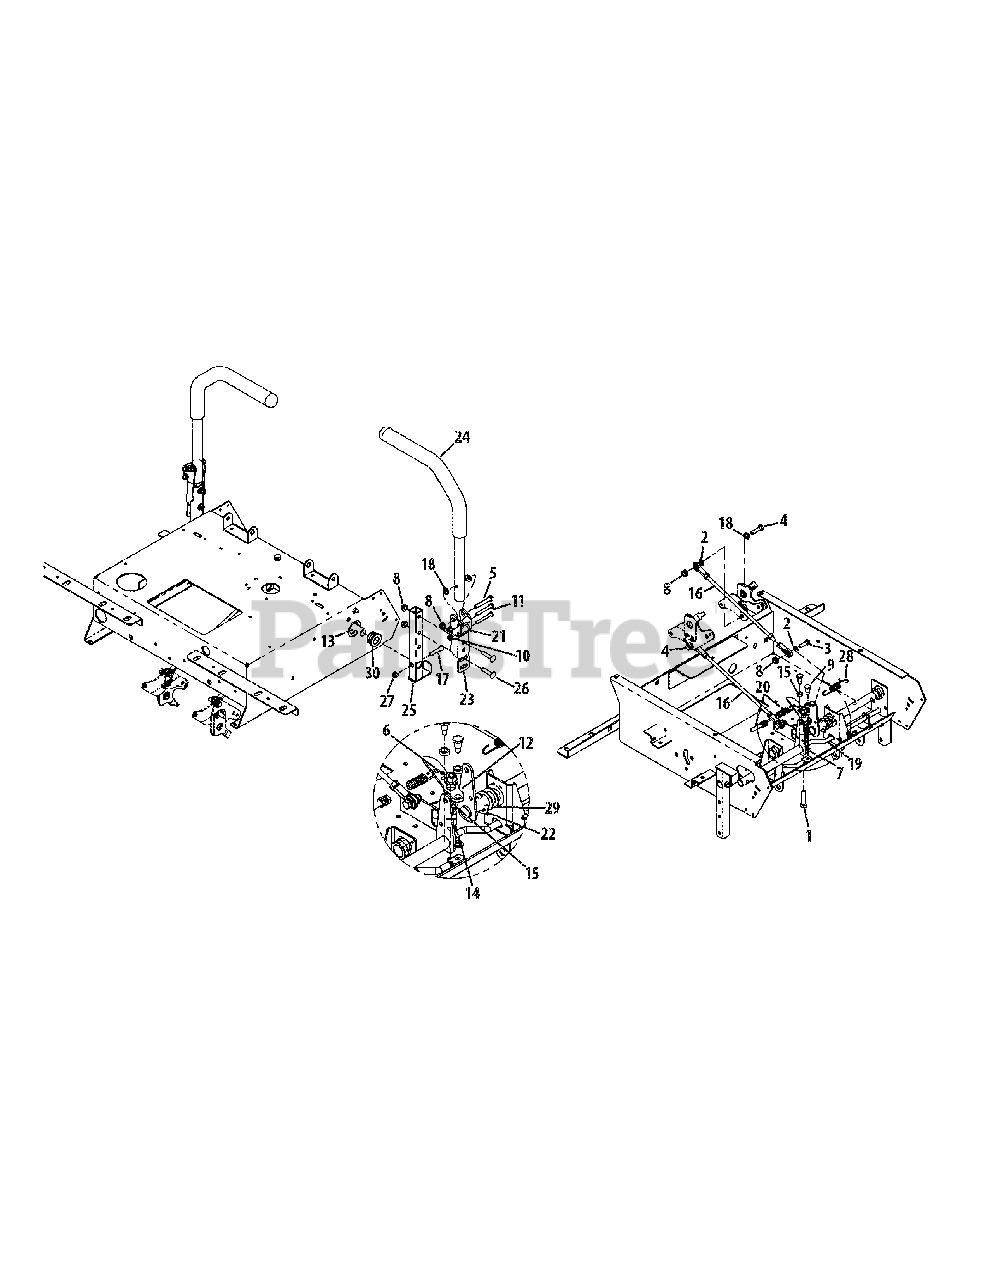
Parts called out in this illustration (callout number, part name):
1	Hex Cap Screw, 3/8-16 x 1-1/2
2	Flat Washer, 5/16
3	Hex Head Cap Screw, 5/16-18 x 1.00
4	Hex Screw, 5/16-18 x 1-1/4
5	Hex Cap Screw, 5/16-18 x 2.00
6	Flange Lock Nut, 3/8-16
7	Flat Washer, 1.4 x .630 x .0515
8	Lock Nut, 5/16-18
9	Shoulder Screw, 1/4-28
10	Hex Flange Lock Nut, 1/4-20
11	Hex Cap Screw, 1/4-20 x 2.00
12	Brake Lever Plate
13	Steering Input Shaft Assembly
14	Spacer, .385 x .625 x .869
15	Spacer, .380 x .563 x .196
16	Steering Link Rod
17	Socket Head Capscrew, 5/16-18 x 1.25
18	Bushing, .310 x .172 x .688 x .06
19	Control Lock Rod
20	Control Cable Lock Out
21	Spacer, .25 x .38 x 1.13
22	E-Clip Retainer Ring
23	Lapbar Pivot Bracket
24	Lapbar Handle/Grip Assembly
25	Pivot Bracket Weldment
26	Carriage Bolt, 5/16-18 x 1.50
27	Nylock Nut, 5/16-18
28	Extension Spring, .544 x 3.35
29	Flat Washer, .793 x 1.24 x .060
30	Hex Flange Bearing, .752
